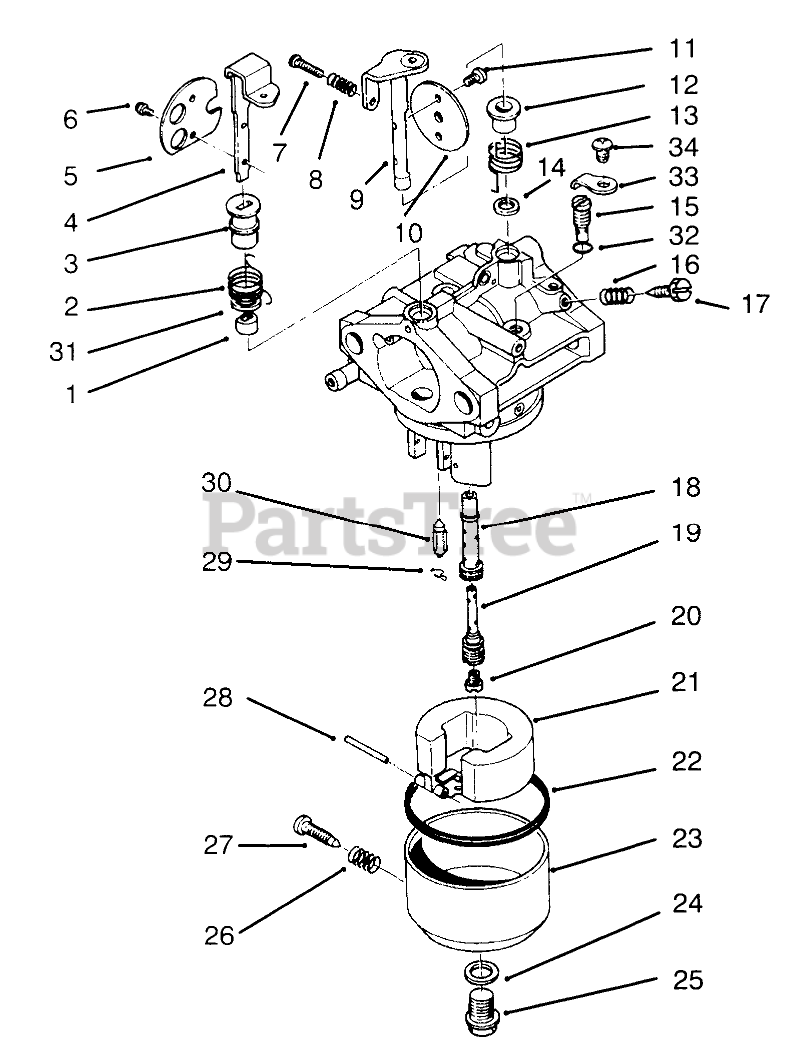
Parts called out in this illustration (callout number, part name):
1	Ring
2	Spring
3	Ring
4	Shaft-Choke
5	Valve-Choke
6	Screw
7	Screw
8	Spring
9	Shaft-Throttle
10	Valve-Throttle
11	Screw
12	Collar
13	Spring
14	Seal
15	Jet
16	Spring
17	Screw
18	Nozzle
19	Pipe-Bleed
20	Jet
21	Float
22	Gasket
23	Chamber-Float
24	Washer
25	Bolt
26	Spring
27	Screw
28	Pin
29	Clip
30	Valve-Needle
31	Seal
32	Gasket
33	Plate
34	Screw
